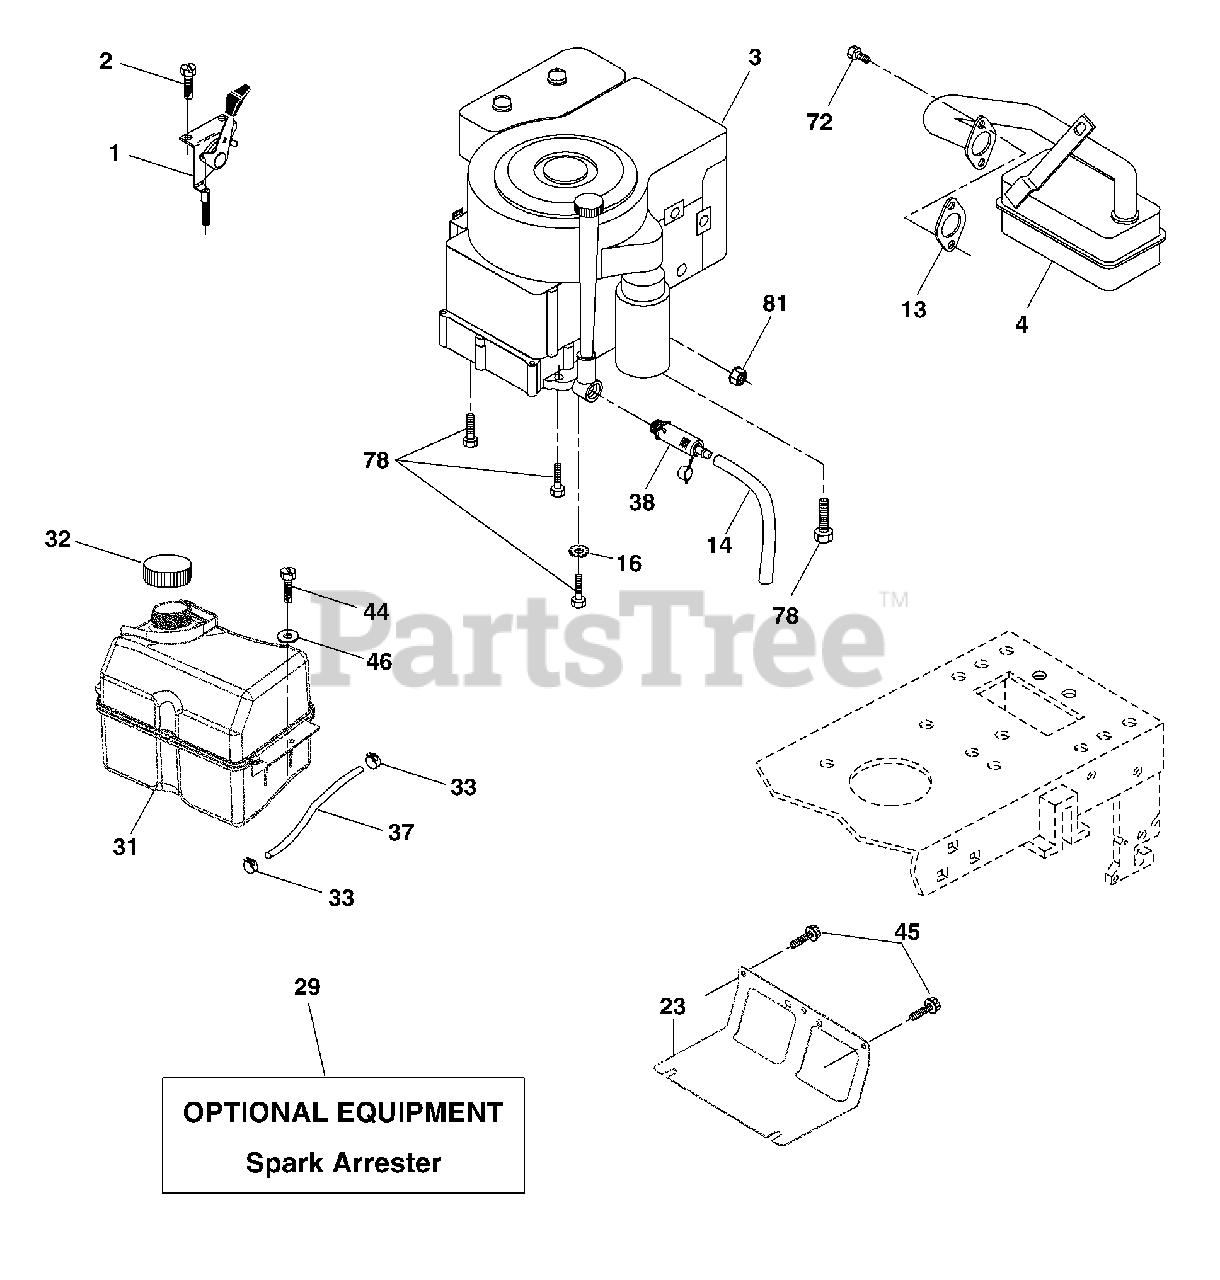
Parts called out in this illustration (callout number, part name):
1	Control Throt /Ch Flag
2	Screw Hex Thd Cut 1/4-20 x 1/2
4	Muffler Exhaust
13	Gasket
14	Tube Drain Oil Easy
16	Washer Lock Ext Tooth 3/8
23	Shield Browning/Debris Guard
29	Arrestor Spark
31	Tank Fuel
32	Cap Asm Fuel W/sym Vented
33	Clamp Hose Blk
37	Line Fuel 20"
38	Plug Drain Oil Easy
44	Screw Hexwsh Thdrol 1/4-20 x 3/4
45	Screw Hex Wsh Thdrol 3/8-16
46	Washer 9/32 x 7/8 x 16ga
72	Screw Socket Head 5/16-18 x 1
78	Screw 3/8-16 x 1-1/4
81	Keps Nut Hex 1/4-20
